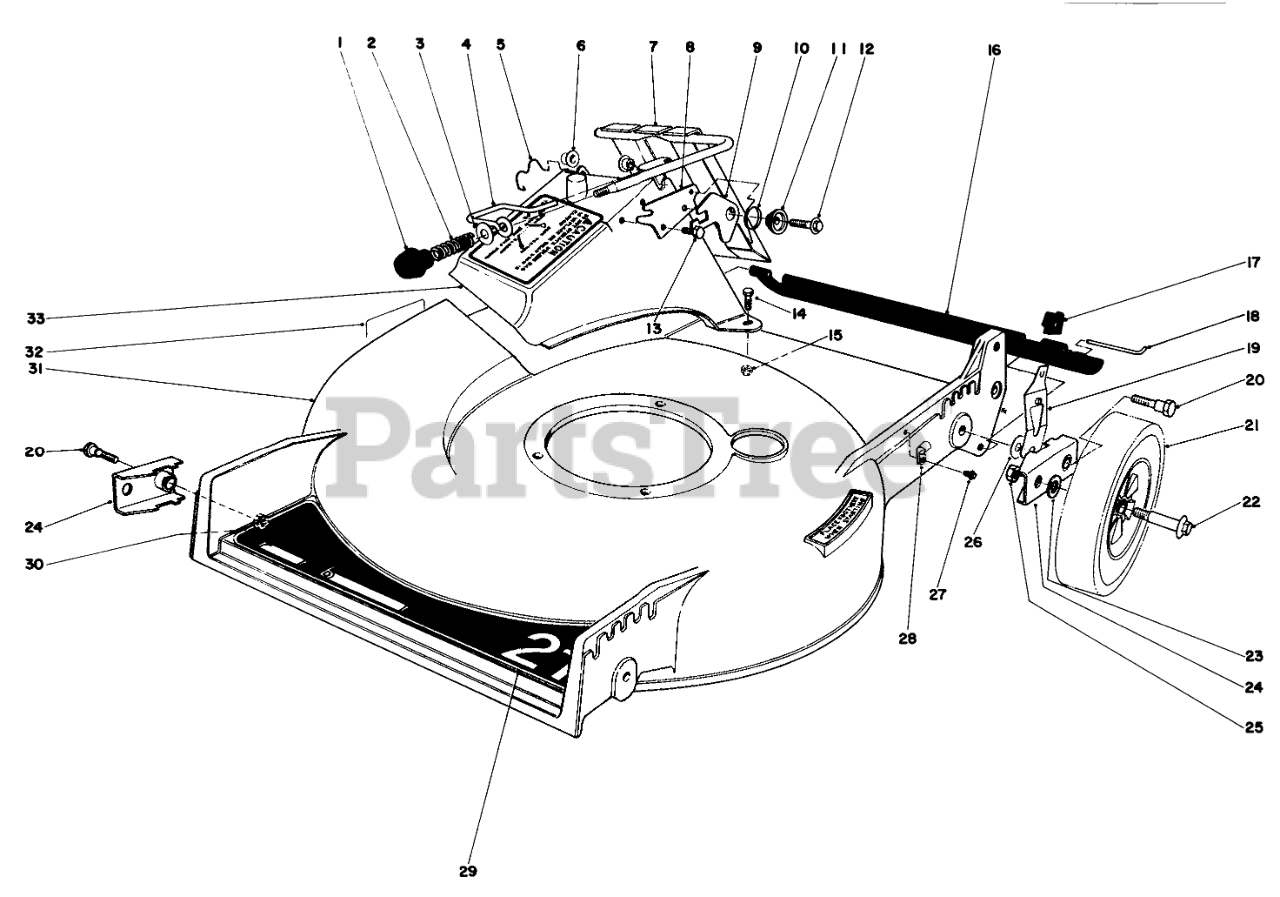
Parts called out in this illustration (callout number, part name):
2	COMPRESSION SPRING
3	WASHER-FLAT
4	DOOR LATCH
5	DOOR RETAINER
6	BUSHING-NYLON
7	DOOR & HANDLE WA
8	DOOR LATCH PLATE
9	SAFETY LATCH
10	TORSION SPRING
11	DOOR SPACER
12	Screw
13	SCREW-HWH
14	SCREW-HH
15	NUT-LOCK, NI
16	SHIELD - TRAILING
17	KNOB-ARM
18	Rod Shield
19	Spring Arm
20	PIVOT SCREW
21	WHEEL TIRE ASM 8 IN
22	BOLT-WHEEL
23	WASHER
24	Pivot Arm
25	Nut
26	WASHER-PIVOT
27	SCREW-HWH
28	CLAMP-NYLON
29	DECK DECAL
30	Nut
31	Deck (Incl. Ref. #32)
32	DECAL-DANGER
33	DISCHARGE CHUTE B
